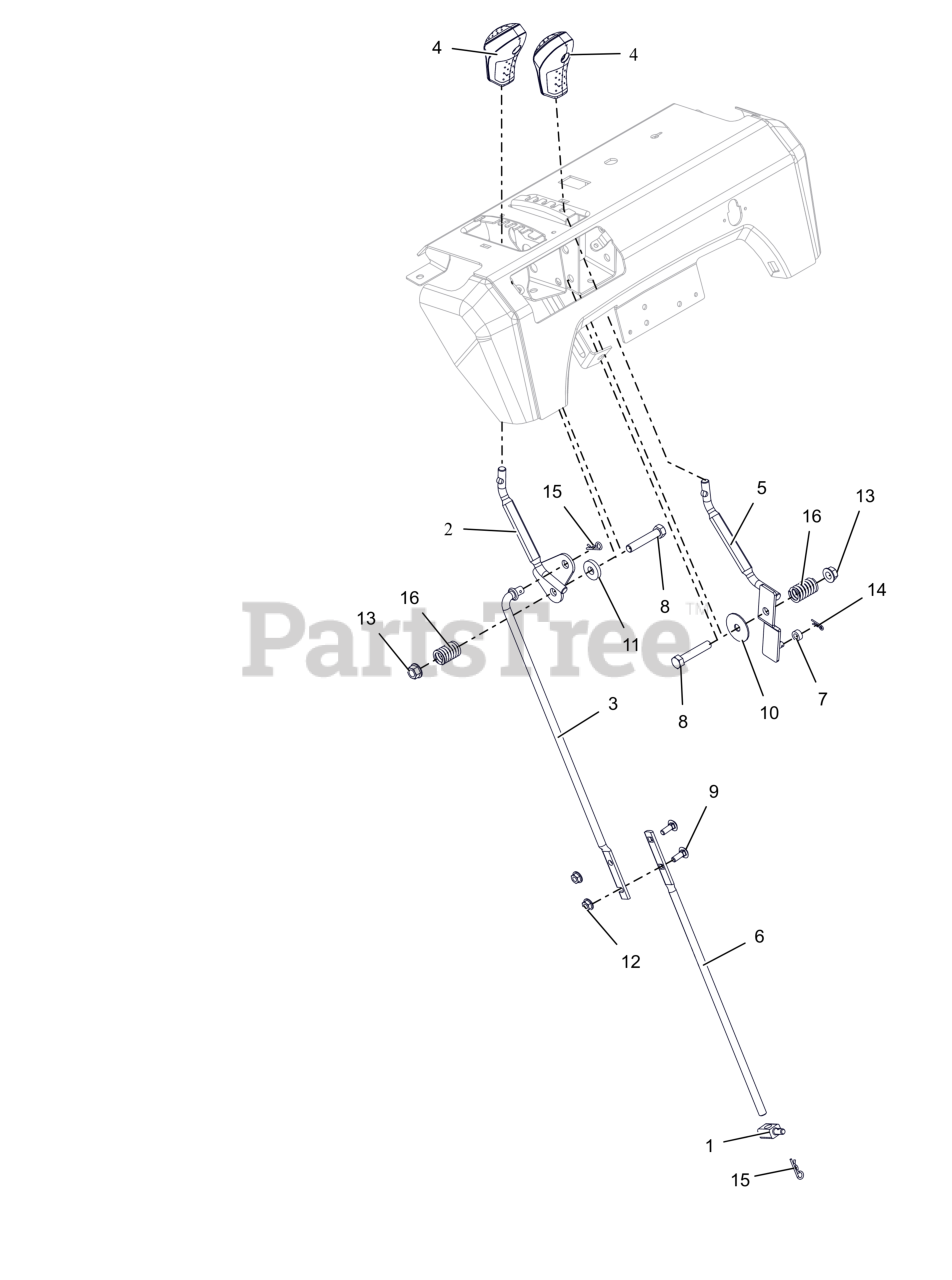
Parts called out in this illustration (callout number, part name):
1	PIVOT,SHIFT ROD .375-16(TRUNN)
2	WELDMENT,LG DASH SPEED CONTROL
3	ROD, SHIFT - UPPER
4	KNOB, CONTROL, DASH
5	WELDMENT,LG DASH DEFL CONTROL
6	ROD, SHIFT - LOWER (LG DASH DLX)
7	BSHG-SLV .265X.500X.219
8	BLT,HEX .38-16X2.00 G5 ZCC
9	BLT, RHSN .25-20X.750 G5 ZCC
10	WSHR,FLT .380X1.50X.062 ZCC
11	WSHR, FLT .406X1.00X.188 ZCC
12	NUT-LK-CTR-FLG .25-20 ZC120
13	NUT-LK-TOP-FLG .38-16 ZC120
14	PIN, HAIR #178 .06X.77 ZCC
15	PIN, HAIR #213 .08X1.19 ZCC
16	SG-COMP .125X.781X1.250
